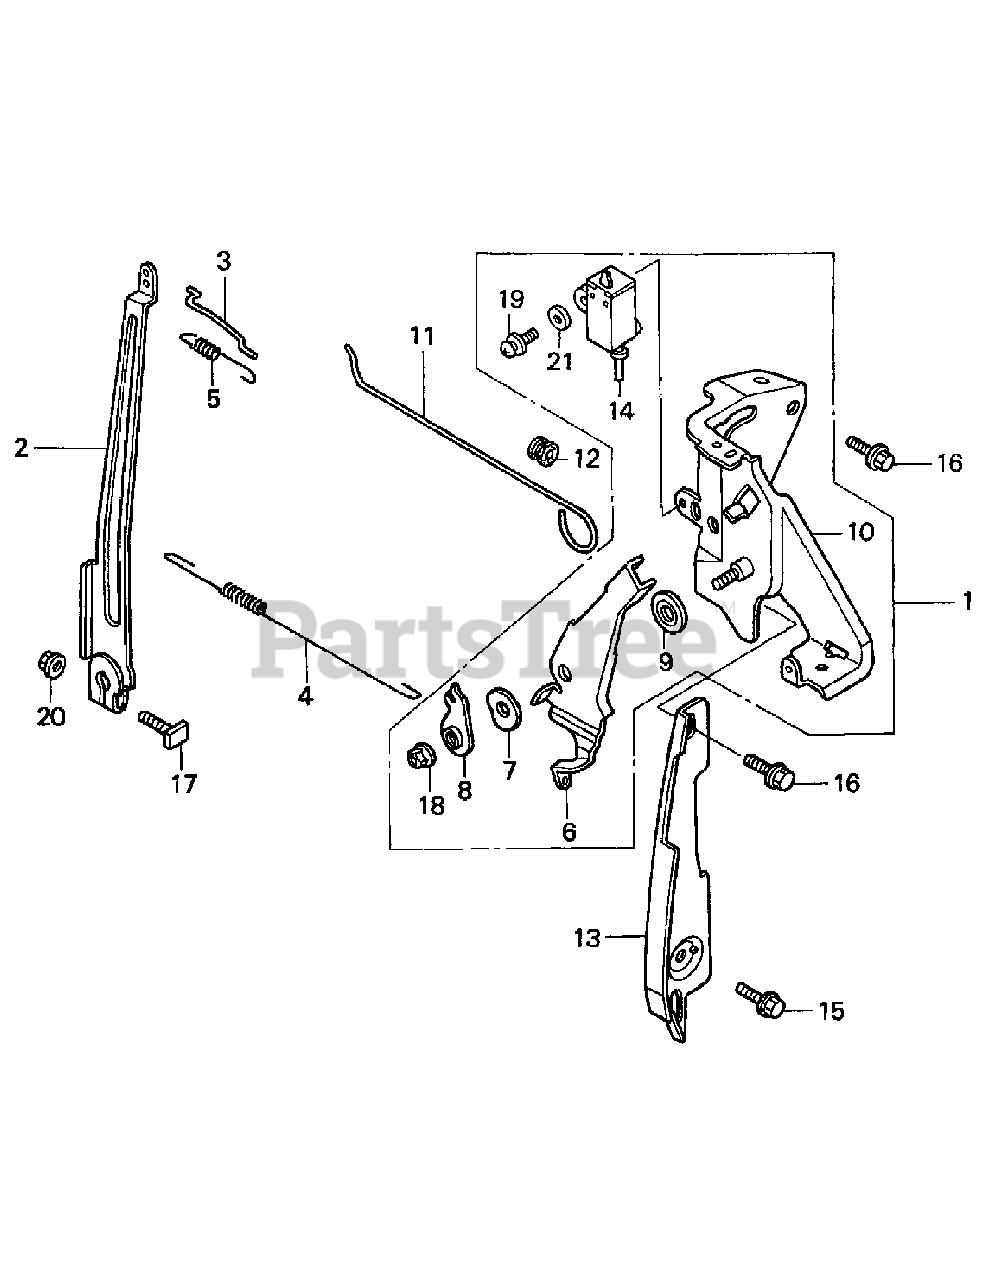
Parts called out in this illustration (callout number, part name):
1	Control Assy.
2	Arm, Governor
3	Rod, Governor
4	Spring, Governor
5	Spring, Throttle Return
6	Lever, Control
7	Spring, Lever
8	Washer, Control Lever
9	Spacer, Control Lever
10	Base Comp., Control
11	Rod, Choke Control
12	Grommet, Choke Rod
13	Plate, Side
14	Switch Assy., Engine Stop (N.O)
15	Bolt, Flange, 6X12 (Ct200)
16	Bolt, Flange, 6X14 (Ct200)
17	Bolt, Governor Arm
18	Nut, Self-Lock, 6Mm
19	Screw-Washer, 4X12
20	Nut, Flange, 6Mm
21	Washer, Plain, 4Mm
